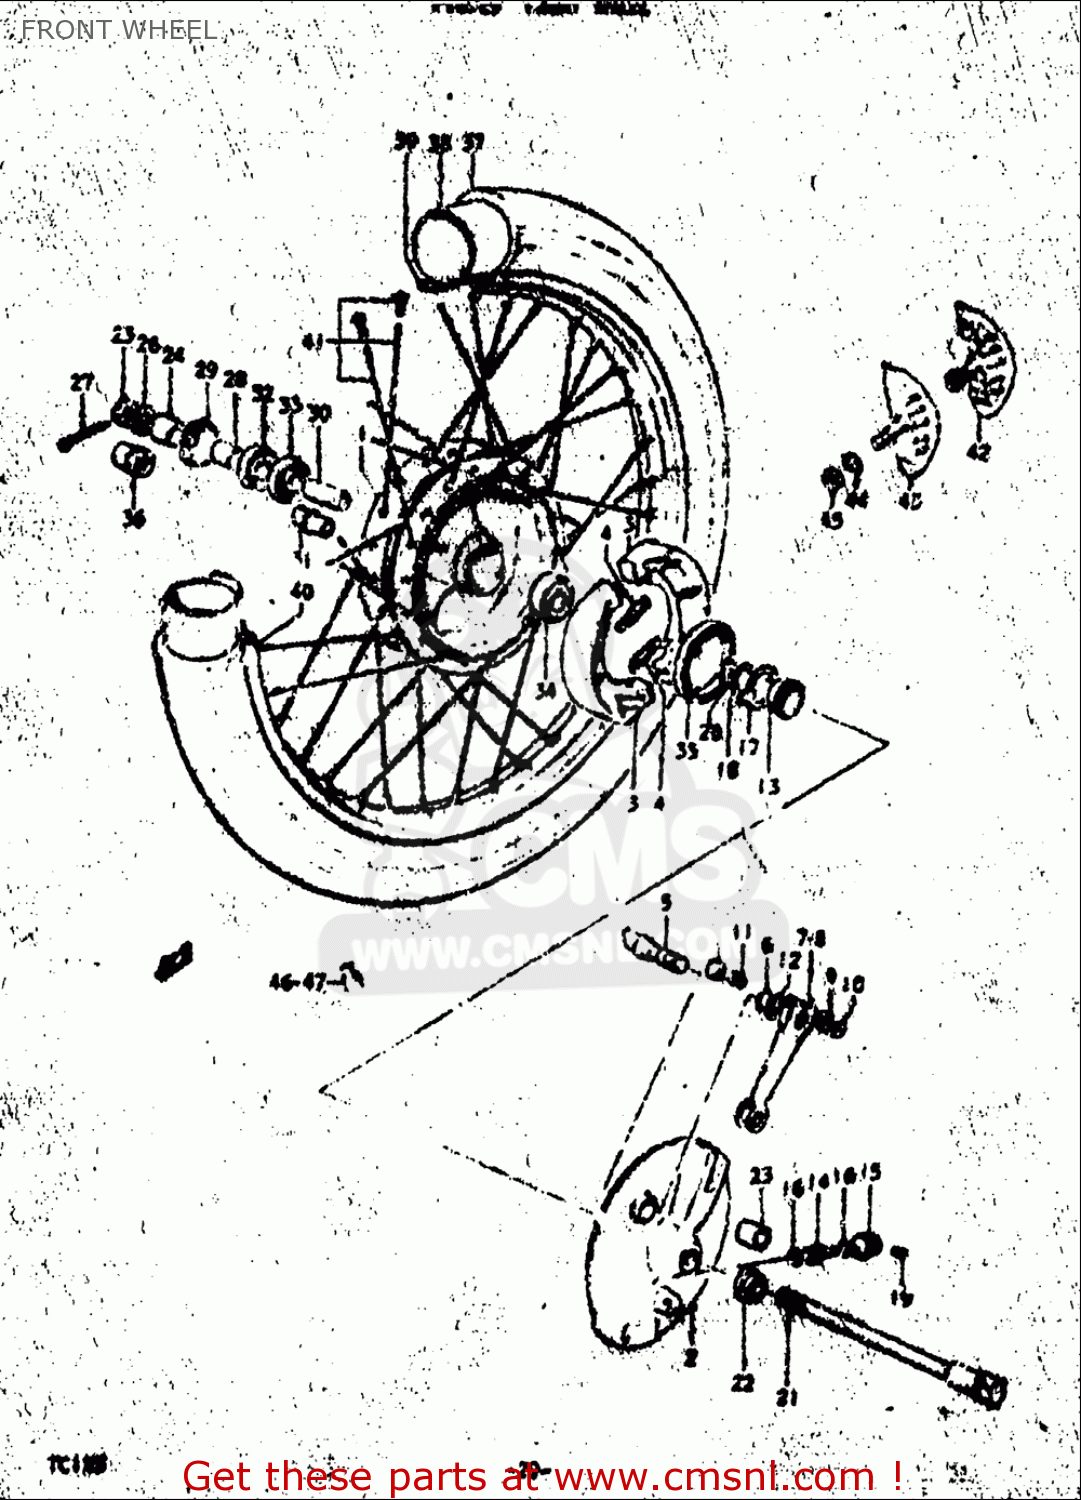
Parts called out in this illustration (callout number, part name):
1	HUB,FR WHEEL
3	SHOE & SPRING SET,BRAKE (NAS)
4	SPRING(L:35.8)
5	CAM,BRAKE
6	O RING(D:2.5,ID:11.4)
9	WASHER
10	NUT
11	BOLT(6X31)
12	WASHER(12.5X20X1)
16	WASHER(5.1X9X0.4)
17	DRIVER,SPEEDOMETER GEAR
18	WASHER(18.5X24X1)
19	SCREW
20	CIRCLIP
23	SPACER (12X20X41)
24	SPACER (12X20X44)
25	NUT 12MM
26	WASHER
27	PIN
28	SPACER(12X18X16.4)
30	SPACER(12.5X19X52)
32	SEAL,OIL(18X32X7)
33	BEARING
34	BEARING
35	SEAL,OIL(43X58X7)
39	PROTECTOR,WHL INR TUBE
40	RIM,FRONT WHEEL (1.40X19)
42	STOPPER,BEAD
44	WASHER
45	NUT
46	BALANCER,WHEEL (30G)
47	BALANCER,WHEEL (50G)
